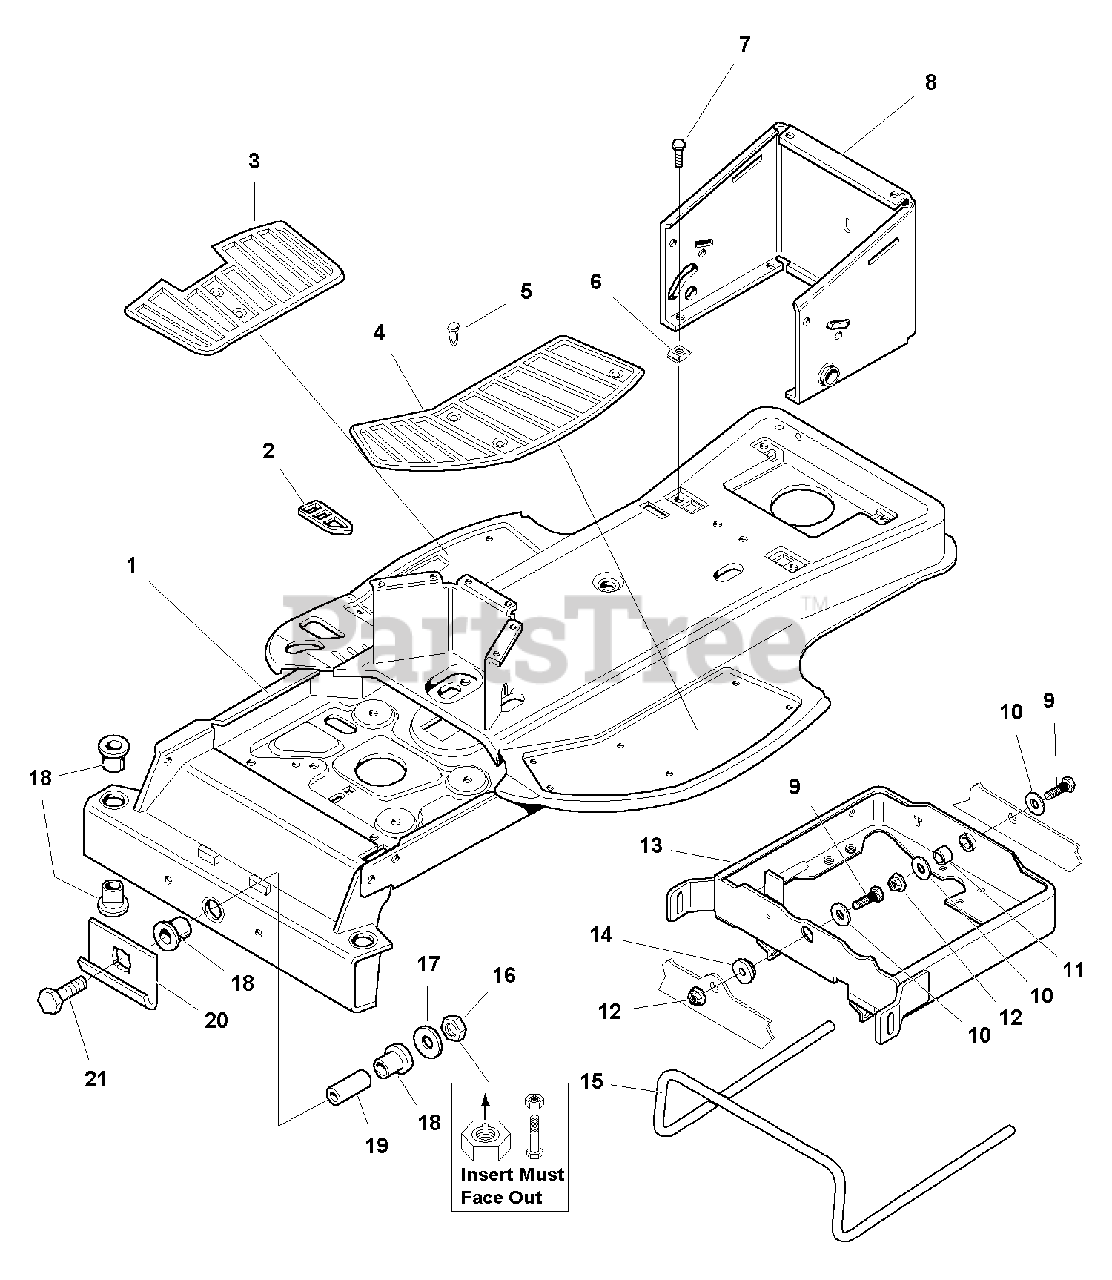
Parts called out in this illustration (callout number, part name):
1	FRAME ASSEMBLY
3	PAD, Footrest RH
4	PAD, Footrest LH
5	FASTENER, Panel
6	NUT, Speed 5/16-18
7	SCREW, Hex Head Flange Lock, 5/16-18 x 3/4
8	WRAPPER ASSEMBLY, Hydro
9	CAPSCREW, Hex Head, 1/2-13 x 1-1/2
10	WASHER, 1/2
12	NUT, Hex , 1/2-13
13	CARRIER ASSEMBLY, Hydro
15	BAR, Torsion
16	NUT, Hex Lock Aluminum Insert, 3/8-16
17	WASHER, 3/8
18	BUSHING, 3/4, Nylon
20	HITCH, Hook "J"
21	CAPSCREW, Hex Head, 3/8-16 x 3
